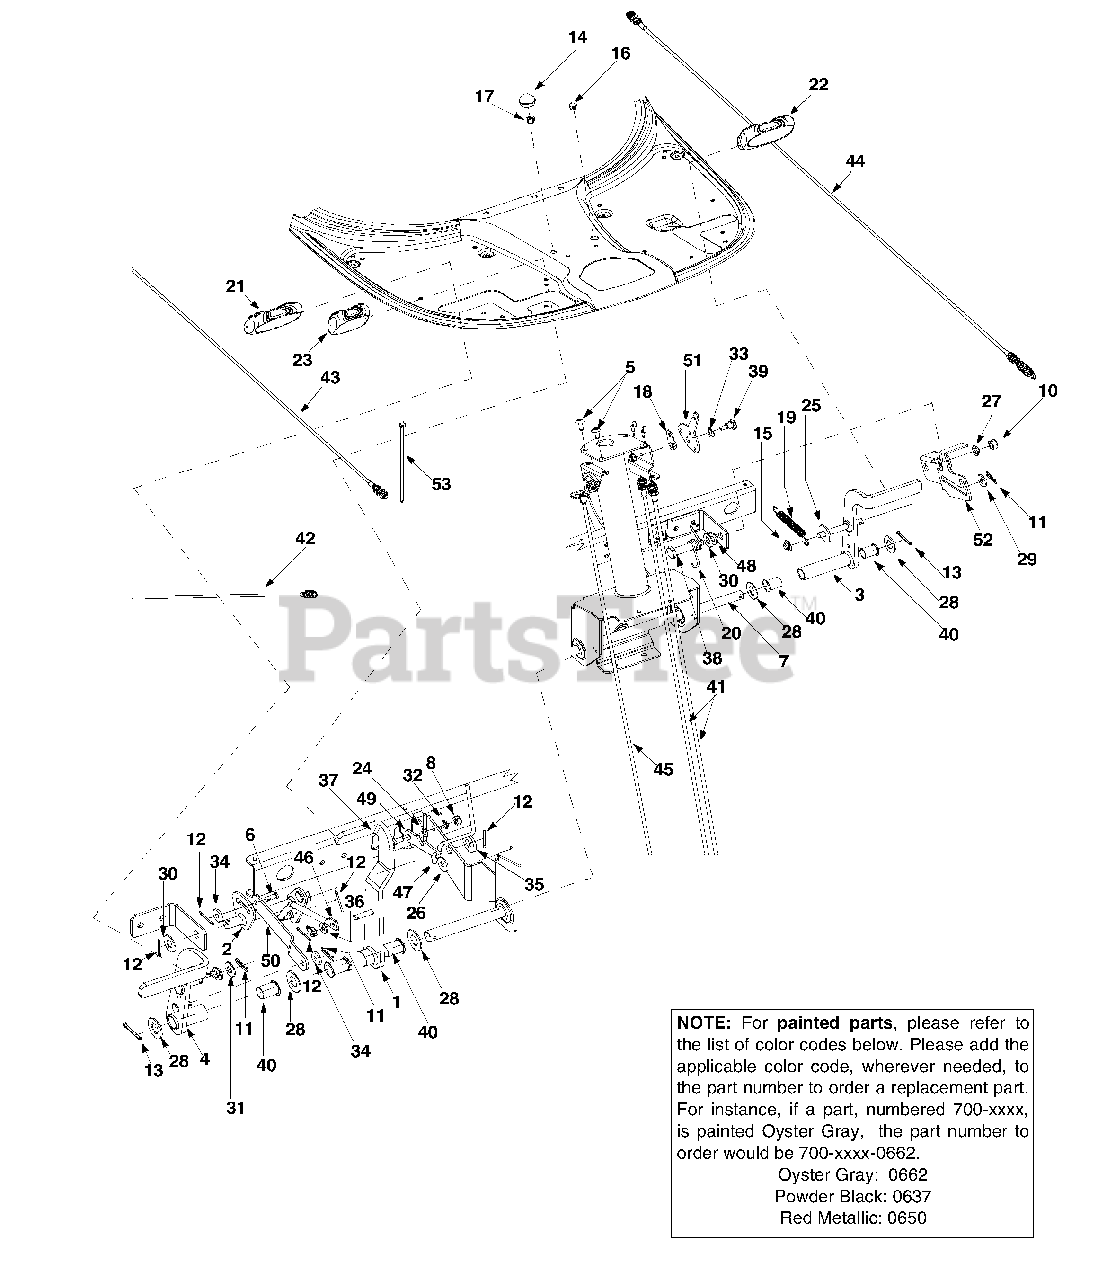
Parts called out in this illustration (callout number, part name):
6	Clevis Pin
8	Hex Nut 1/4-20
10	Hex Nut 3/8-16
11	Internal Cotter Pin
12	Hairpin Clip
13	Hairpin Clip
17	Snap-on Bushing
19	Extension Spring
20	Torsion Spring
24	Flat Washer 3/8 X .620 X .033
25	Flat Washer.411 x 1.25" x .100
30	Flat Washer .510 X 1.00 X .060
32	Lock Washer
33	Spring Washer
34	Flat Washer
35	Flat Washer .531 X 1.062 X .134
36	Flat Washer .271 X .630 X .065
37	Shoulder Screw .375 Dia X .18
38	Shoulder Screw
39	Shoulder Screw .375 X .380 X 1/4-20
40	Flange Bearing
41	Shift Cable
42	Variable Drive Cable
43	Brake Cable
44	Deck Cable
45	Throttle Choke Cable: 67"
47	Brake Lock Out Rod
48	Shoulder Spacer
